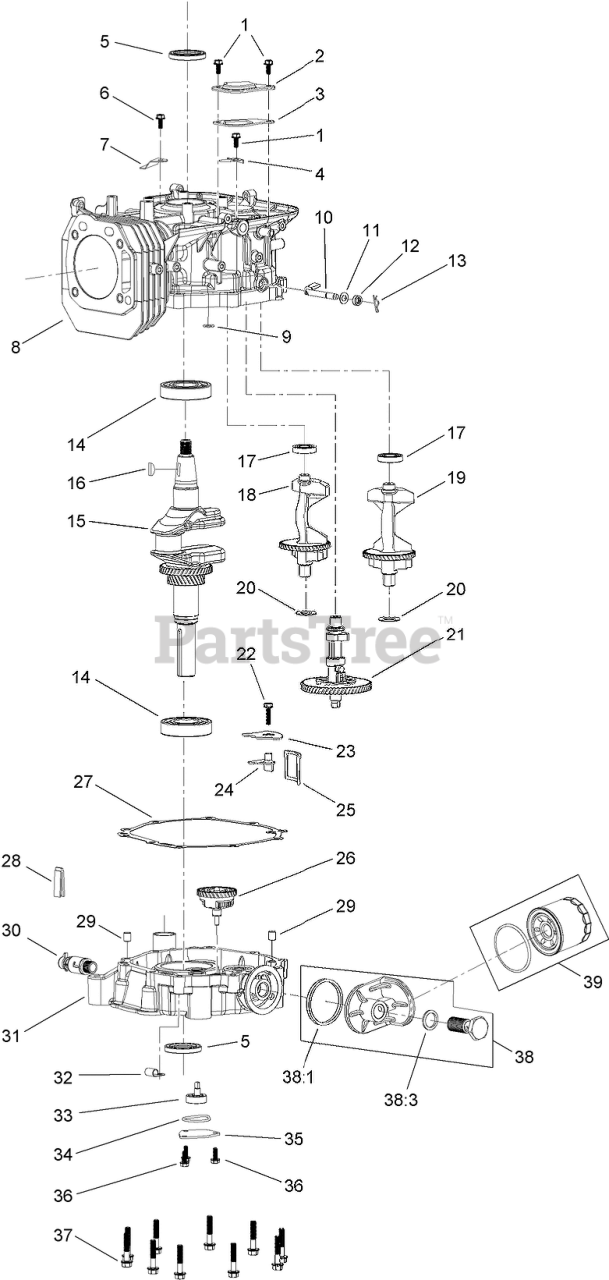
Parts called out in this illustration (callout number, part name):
1	SCREW-HHF
2	PLATE-BREATHER
3	GASKET-BREATHER
4	VALVE-REED
5	SEAL-OIL
6	SCREW-HHF
7	RETAINER
8	CRANKCASE
9	O-RING
10	SHAFT-GOVERNOR
11	WASHER-PLAIN
12	SEAL-OIL
13	PIN-HAIR
14	BEARING-BALL
15	CRANKSHAFT
16	KEY-WOODRUFF
17	BEARING-BALL
18	BALANCER-RH
19	BALANCER-LH
20	WASHER
21	CAMSHAFT
22	SCREW-HHF
23	COVER-STRAINER, OIL
24	PLATE-BAFFLE, OIL
25	STRAINER-OIL
26	GEAR-GOVERNOR
27	GASKET-CRANKCASE
28	DEFLECTOR-OIL, RUBBER
29	PIN-DOWEL
30	VALVE-DRAIN, OIL
31	COVER-CRANKCASE
32	CLAMP-J
33	OIL PUMP ASM
34	SEAL-PUMP, OIL
35	COVER-PUMP, OIL
36	SCREW-HHF
37	SCREW-HHF
38	OIL ADAPTOR KIT
38:1	SEAL-ADAPTOR, OIL
38:3	WASHER-FILTER, OIL
39	FILTER-OIL
